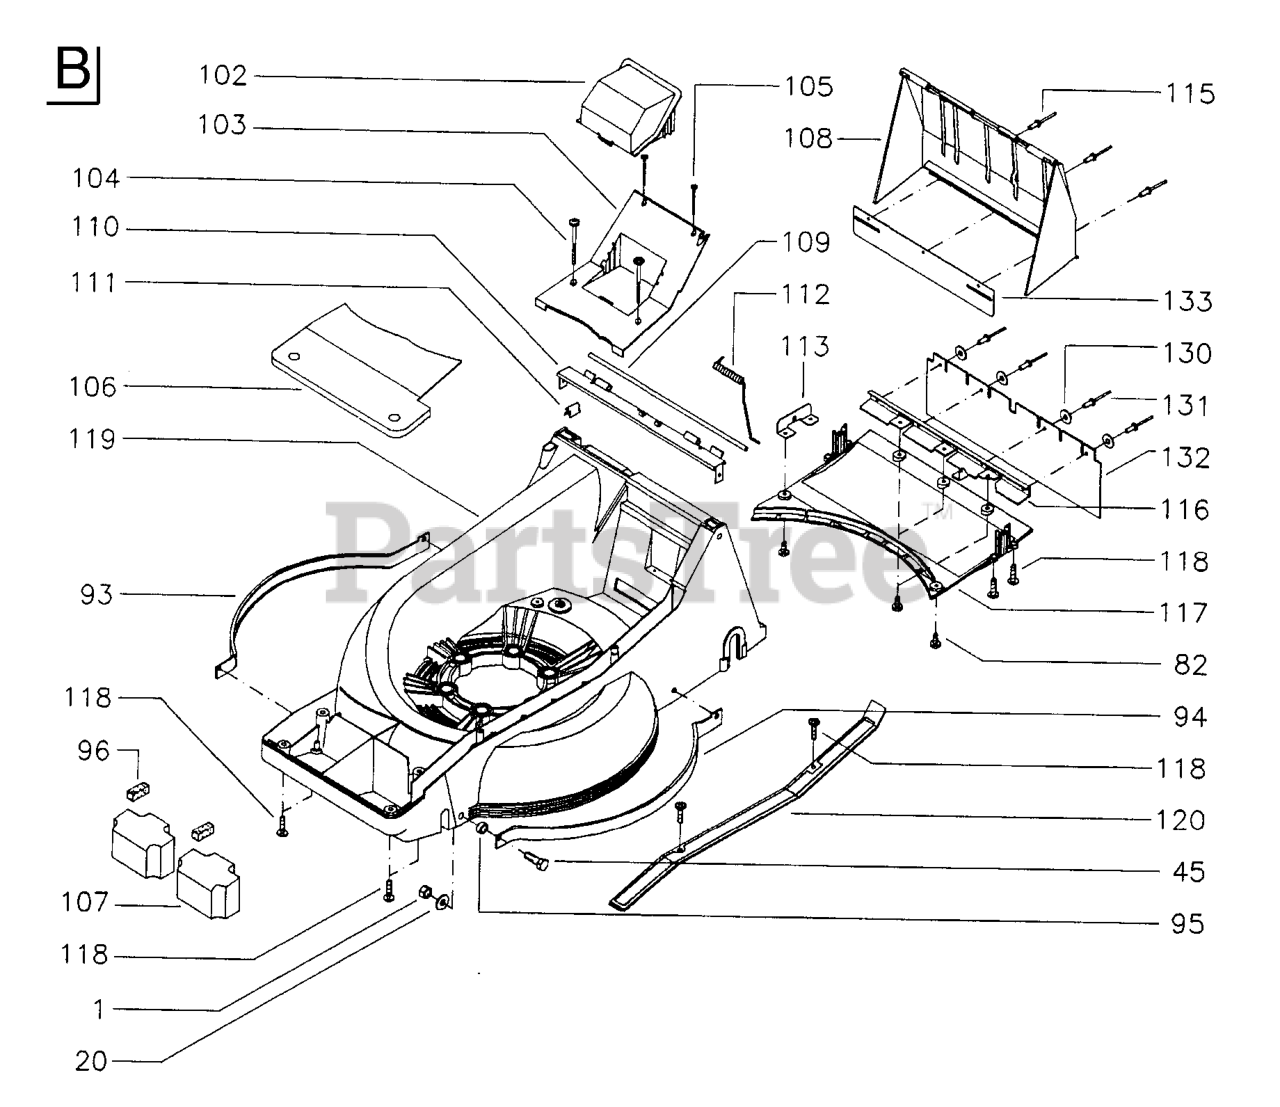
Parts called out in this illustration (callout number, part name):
1	LOCKNUT M8
45	SCREW M6S 8X25
93	DECK PROTECTOR RH
94	DECK PROTECTOR LH
106	DECK FRONT COVER
107	COUNTERWEIGHT
110	BRACKET
113	BRACKET
120	COVER
